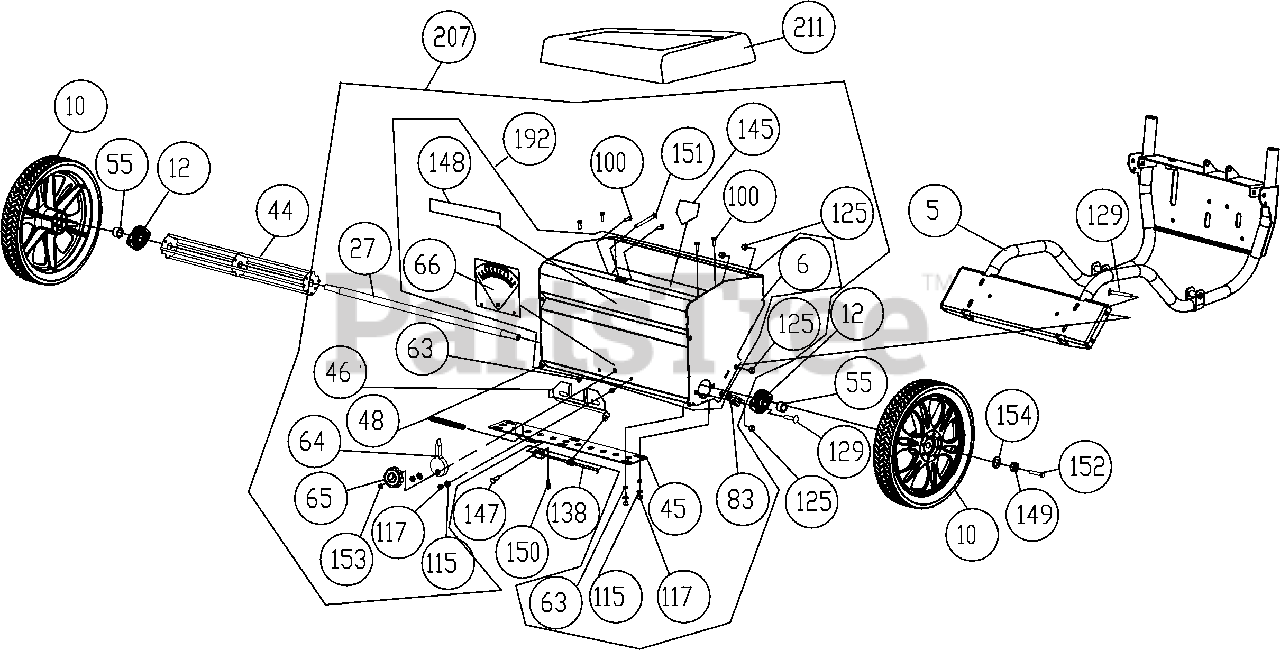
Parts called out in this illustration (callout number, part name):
5	FRAME SUPPORT OS900SP WA
6	SEED BOX WA
10	FRONT WHEEL 14" ASSY
12	BEARING & FLANGETTE ASSY
27	AXLE SEED BOX
44	WHEEL PADDLE SEED WA
45	PLATE SEED CONTROL OS900SP
46	BRACKET CONTROL SEED RATE
48	SPRING EXTENSION .5 X 5.00
55	SPACER SEED BOX AXLE OS900SP
63	SPACER SEED PLATE OS900SP
64	DIAL SEED INDICATOR
65	KNOB 5/16"-18 X 5/8" FLUTED
66	LABEL SEED FLOW RATE
83	CLAMP ROUTING FUEL LINE
100	SCREW 1/4" - 20 X .75 HWH
115	WASHER 1/4" SAE
117	LOCK NUT 1/4-20
125	NUT 5/16"-18 SER HEX WASHER FLNG ZP
129	BOLT CARRIAGE 5/16"-18 X 3/4" ZP
138	CABLE CLUTCH SEEDING CONTROL
145	LABEL WARNING OPEI
147	PIN CLEVIS 1/4" X .61
148	LABEL BADGING OS900SP
149	WASHER LOCK 5/16" TWISTED TOOTH HEAVY
150	PIN CLIP HITCH 0.051 X 3/4"
151	BOLT CARRIAGE 5/16"-18 X 1 1/4" ZP
152	SCREWCAP 5/16"-18 X 3/4" HCS ZP
153	NUT LOCK 5/16"-18 LT WT TH ZP
154	WASHER FENDER 5/16"
192	SEED BOX WAS OS900SP W/LABELS
207	SEED BOX SERVICE KIT
211	SEED BOX BONNET
